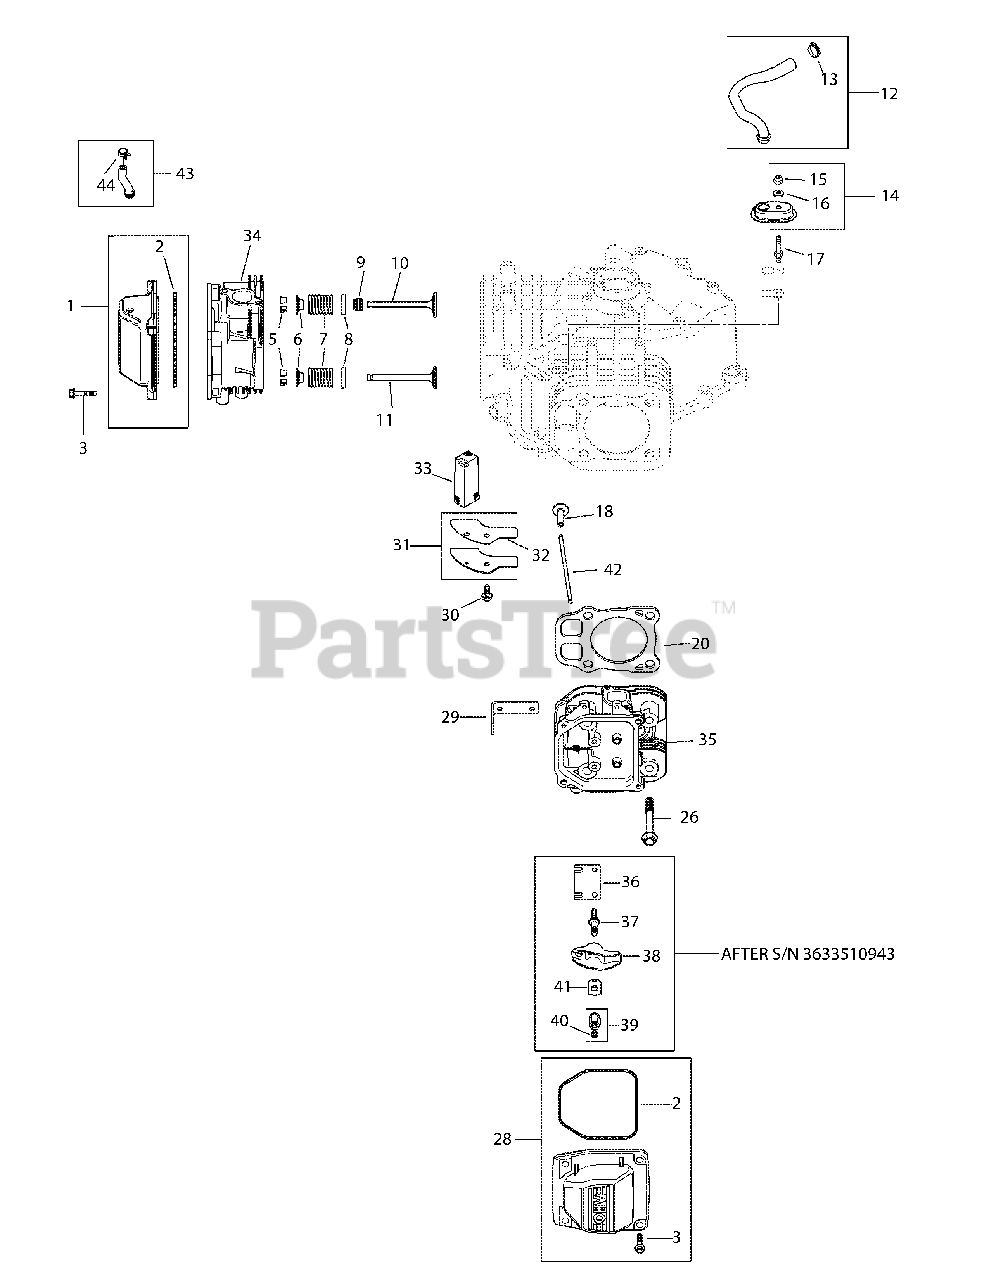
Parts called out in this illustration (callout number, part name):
1	Breather Valve Cover Kit (Inc. 2)
2	Valve Cover O-Ring
3	Flg. Screw, M6 X 1.0 X 30
5	Retainer Kit
6	Valve Spring Cap
7	Valve Spring
8	Spring Retainer
9	Valve Stem Seal
10	Intake Valve (Std)
11	Exhaust Valve (Std)
12	Kit, Breather Hose Kit (Inc. 13)
13	Hose Clamp, 1.2
14	Breather Housing Kit (Inc. 15, 16)
15	Lock Nut, M 5 X .8
16	Sealing Washer
17	Breather Cover Stud
20	Cylinder Head Gasket Kit
26	Flg. Screw, M 10 X 1.5 X 90
28	Breather Valve Cover Kit (Inc. 2 & 3)
29	Lifting Strap
30	Flg. Thd. Frm. Screw, M6 X 1.0 X 16
31	Breather Cover Kit (Inc. 32)
33	Breather Filter
34	#1 Cylinder Head Assembly Kit
35	#2 Cylinder Head Assembly Kit
39	Hex Nut Assembly (Includes 39)
41	Rocker Arm Pivot
43	Fuel Pump Hose w/ Clamp Kit (Inc. 44)
